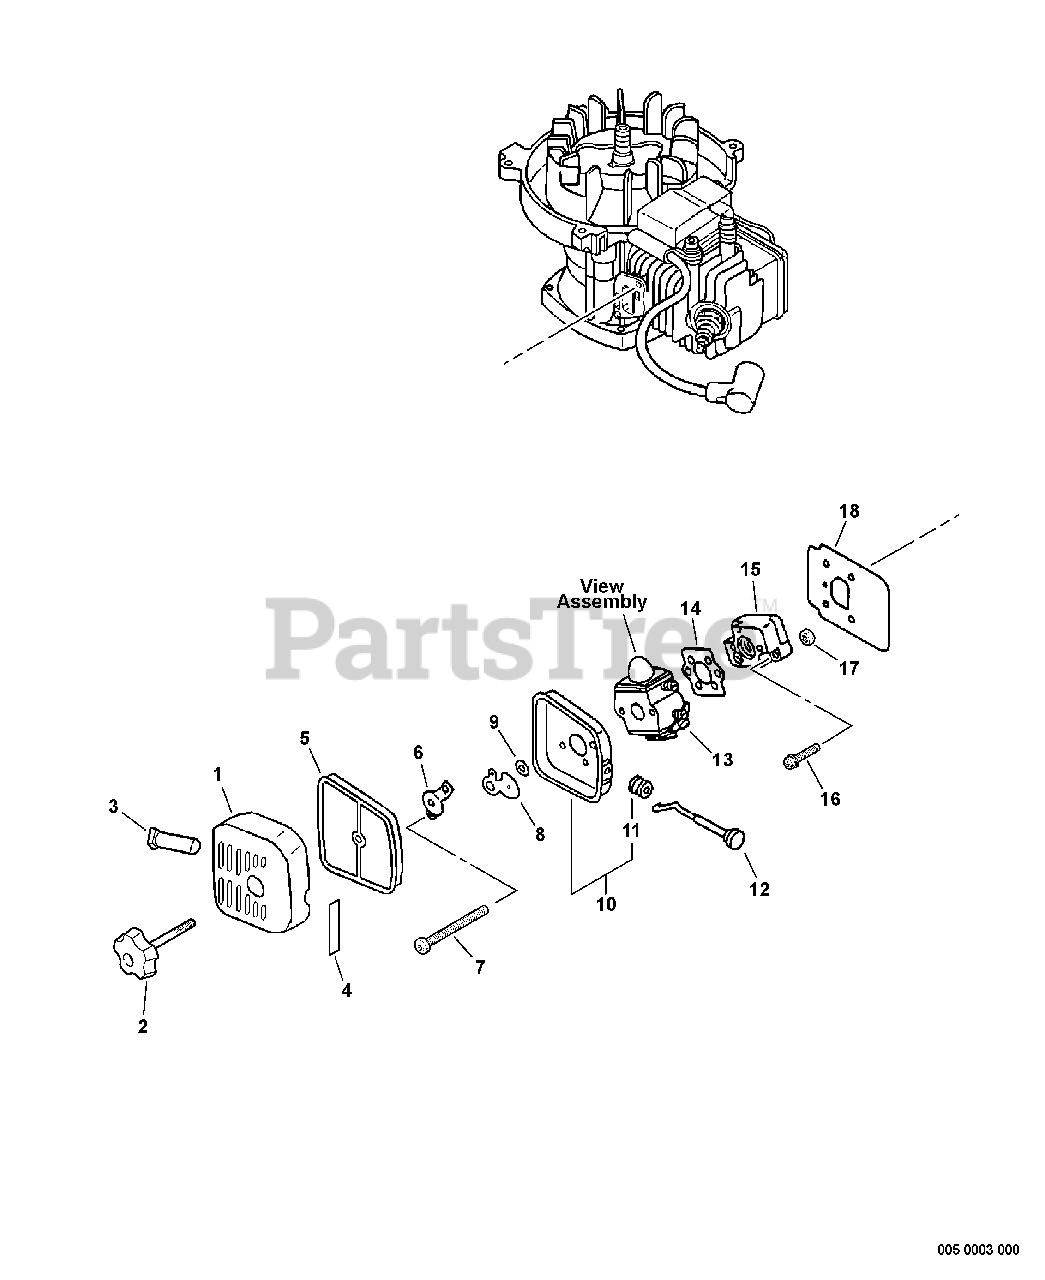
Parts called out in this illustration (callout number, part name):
1	COVER, AIR FILTER
2	THUMBSCREW
4	LABEL - CHOKE
5	FILTER, AIR - HEAVY DUTY
6	PLATE, PREVENT
7	SCREW - 5X57
8	SHUTTER, CHOKE
9	WASHER - 5
10	CASE, AIR FILTER
12	ROD, CHOKE
13	CARBURETOR C1U-K82
14	GASKET, INTAKE
15	INSULATOR, INTAKE
16	SCREW - 5X20
18	SHIELD, INTAKE
